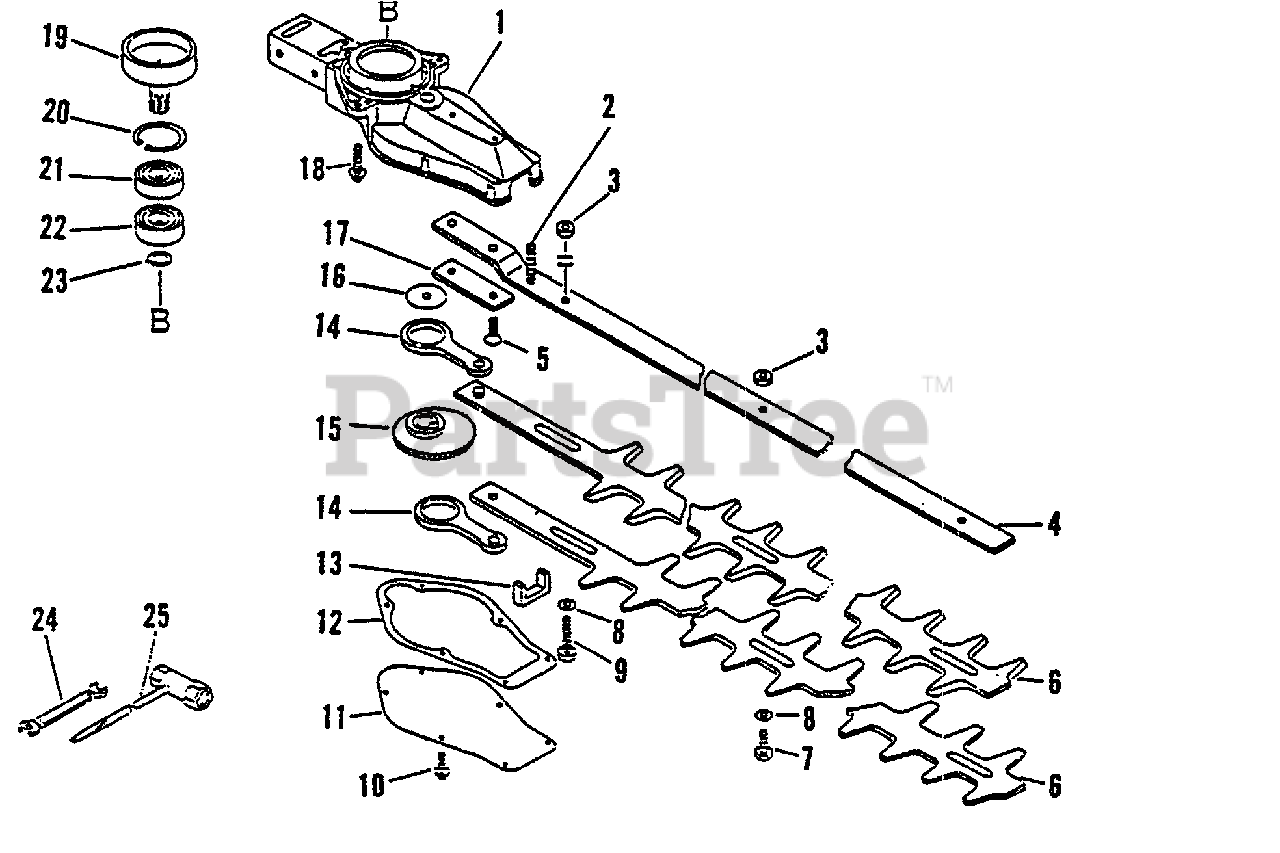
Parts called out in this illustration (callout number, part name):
1	CASE, GEAR
2	SCREW 5×30
3	NUT, LOCK 6
4	BAR, FRAME
5	SCREW 6×18
7	BOLT, CUTTER
8	WASHER 6.5×15.5×0.6
9	BOLT 6×35
10	SCREW 4×10
11	LID, GEAR CASE
12	GASKET, GEAR CASE
14	ROD, CONNECTING
17	PLATE, EYE
18	SCREW 5×20
19	DRUM, CLUTCH
20	RING, SNAP 35
21	BEARING, BALL 6202
22	BEARING, BALL 6202
23	RING, SNAP 14
24	T-WRENCH 13×19×180
25	SPANNER 8×10
